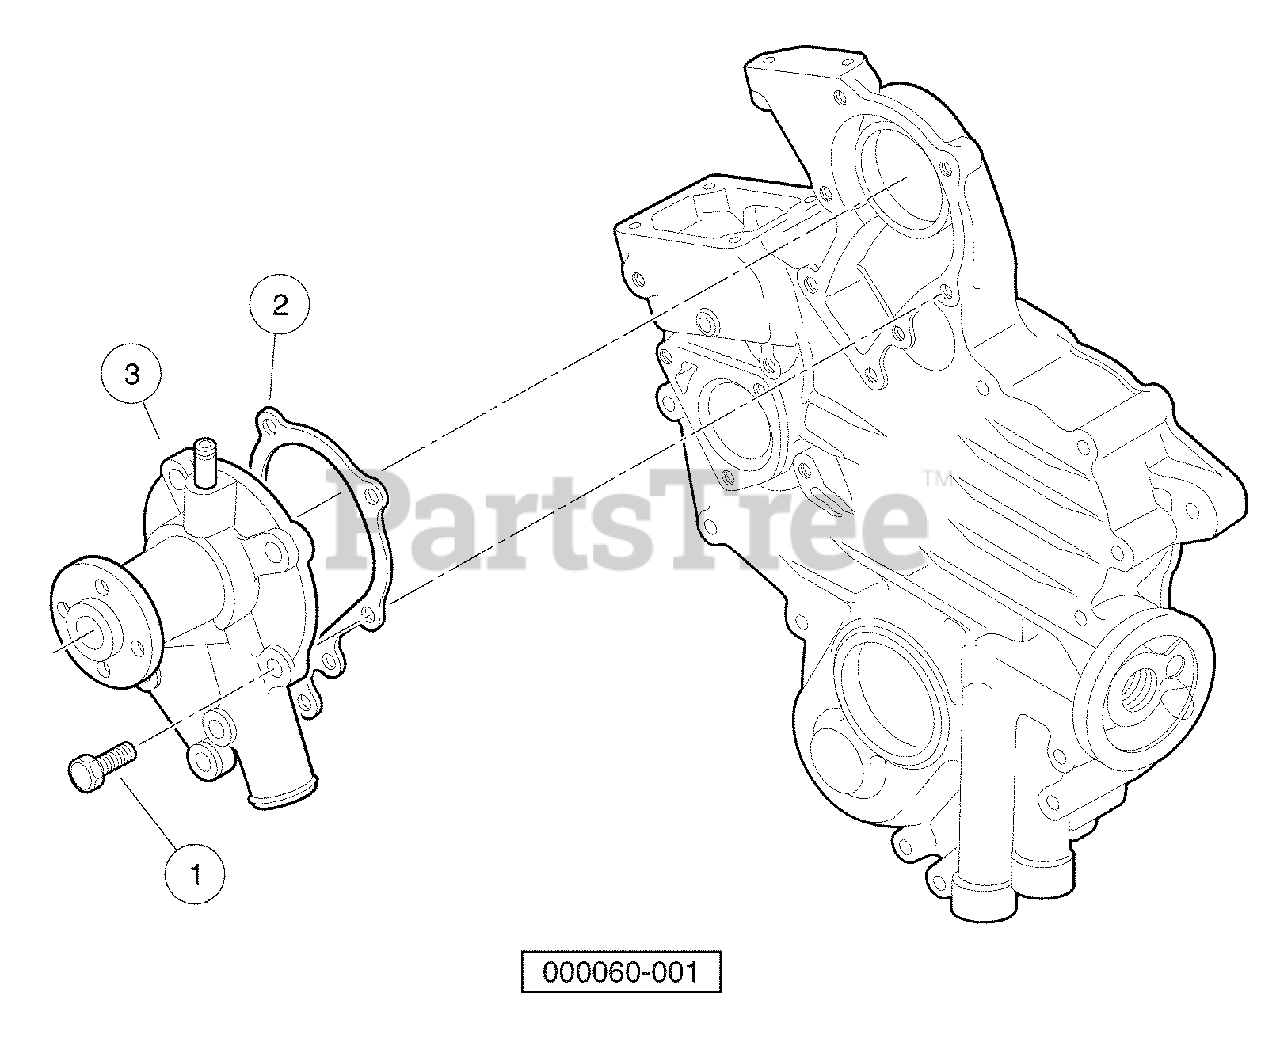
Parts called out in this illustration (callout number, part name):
1	Bolt, M6 X 1 X 22
2	Gasket, Water Pump, D722
3	Water Pump Assembly
